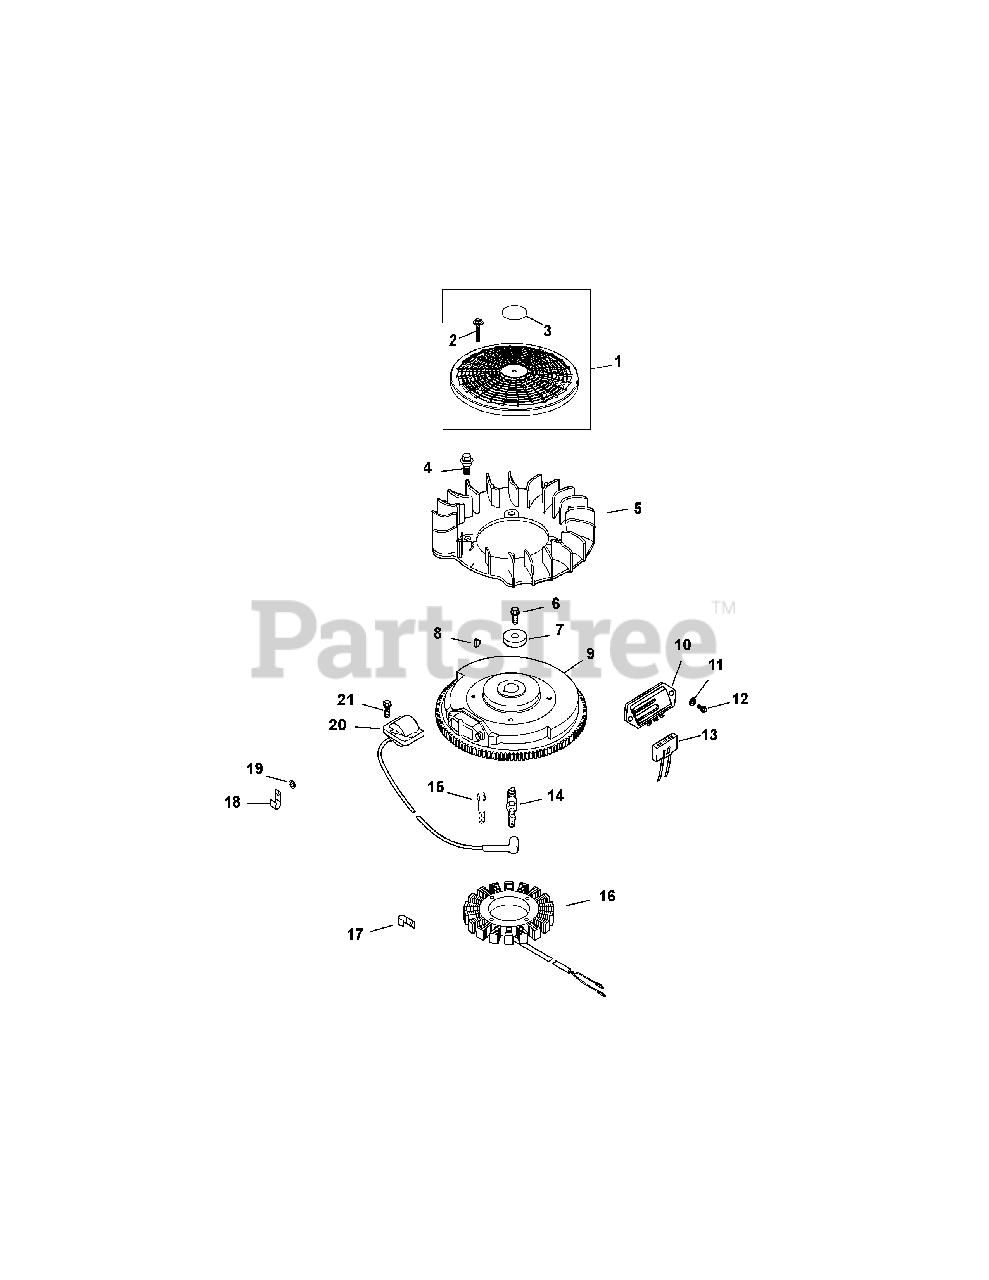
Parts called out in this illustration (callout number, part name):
1	KIT, GRASS SCREEN (includes 2,3)
2	SCREW, FLG SEMS M4X.7X25
3	DECAL, GRASS SCREEN
4	BOLT, SHOULDER
6	SCREW, FLG M10X1.5X45
7	WASHER, FLAT 13/32''
8	KEY, 3/16'' X 5/8''
9	FLYWHEEL
10	REGULATOR/RECTIFIER
11	WASHER, FLAT 3/16''
12	SCREW, PHL HD #11-16X7/8''
14	PLUG, SPARK (STD)
15	SCREW, THD FRM M5X0.8X25
16	KIT, 15 / 20 AMP STATOR
17	CLIP, TUBE & WIRING (KM)
18	CLIP, CABLE
19	WASHER, FLAT 1/4'' (O.D. 1/2'')
20	IGNITION, MODULE
21	SCREW, SKT THD FRM M5X0.8X25
